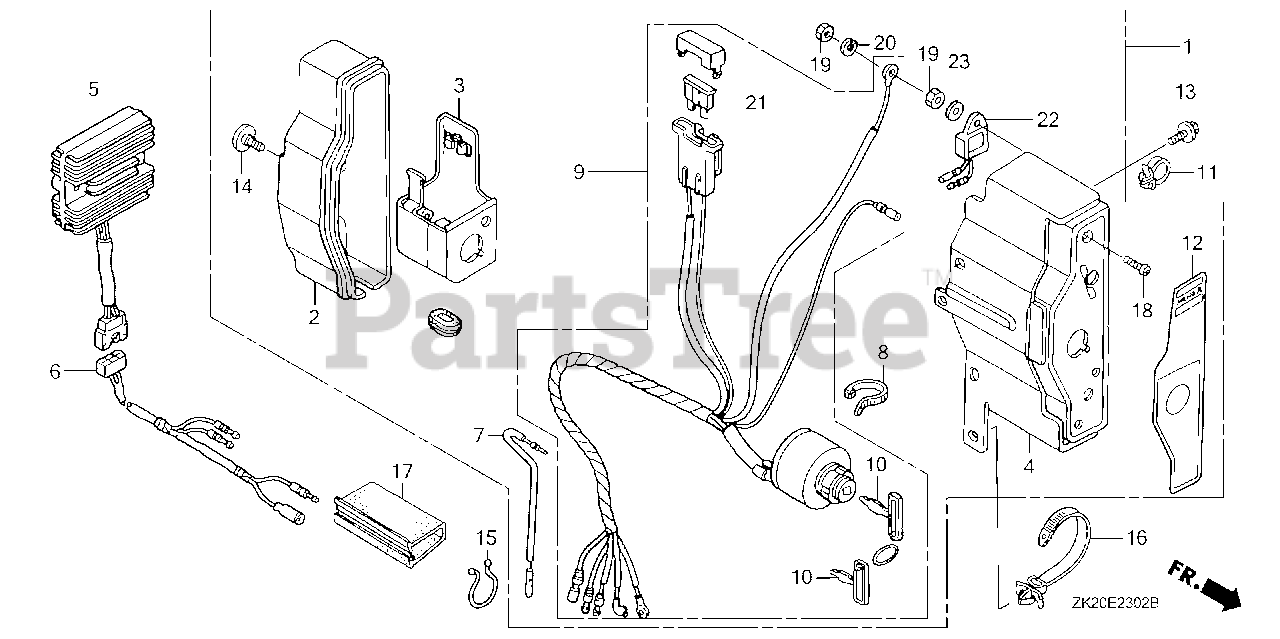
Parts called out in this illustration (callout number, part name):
1	BOX ASSY., CONTROL (18A) *NH1* (EXP-ALERT) (BLACK)
1	BOX ASSY., CONTROL (18A) *R280* (EXP-ALERT) (POWER RED)
2	CASE, CONTROL
3	BRACKET, CASE MOUNTING
4	PANEL, CONTROL *R280* (POWER RED)
5	RECTIFIER ASSY., REGULATOR (20A)
6	SUB-WIRE HARNESS ASSY.
7	SUB-WIRE HARNESS
9	SWITCH ASSY., COMBINATION (18A-CHARGE)
10	KEY (HONDALOCK)
11	HOLDER, STOP SWITCH WIRE
12	MARK, CONTROL BOX (EXTERNAL-REGULATOR)
13	BOLT, FLANGE (6X12) (CT200)
14	SCREW, SPECIAL (6X12)
15	CLIP, PURSE LOCK
16	STRAP, CABLE (118MM) (BLACK)
17	TUBE, FASTENER (30MM)
18	SCREW, PAN (4X12)
19	NUT, HEX. (4MM)
20	WASHER, SPRING (4MM)
21	FUSE, BLADE (25A)
22	ALERT UNIT, OIL
23	WASHER, PLAIN (4MM)
